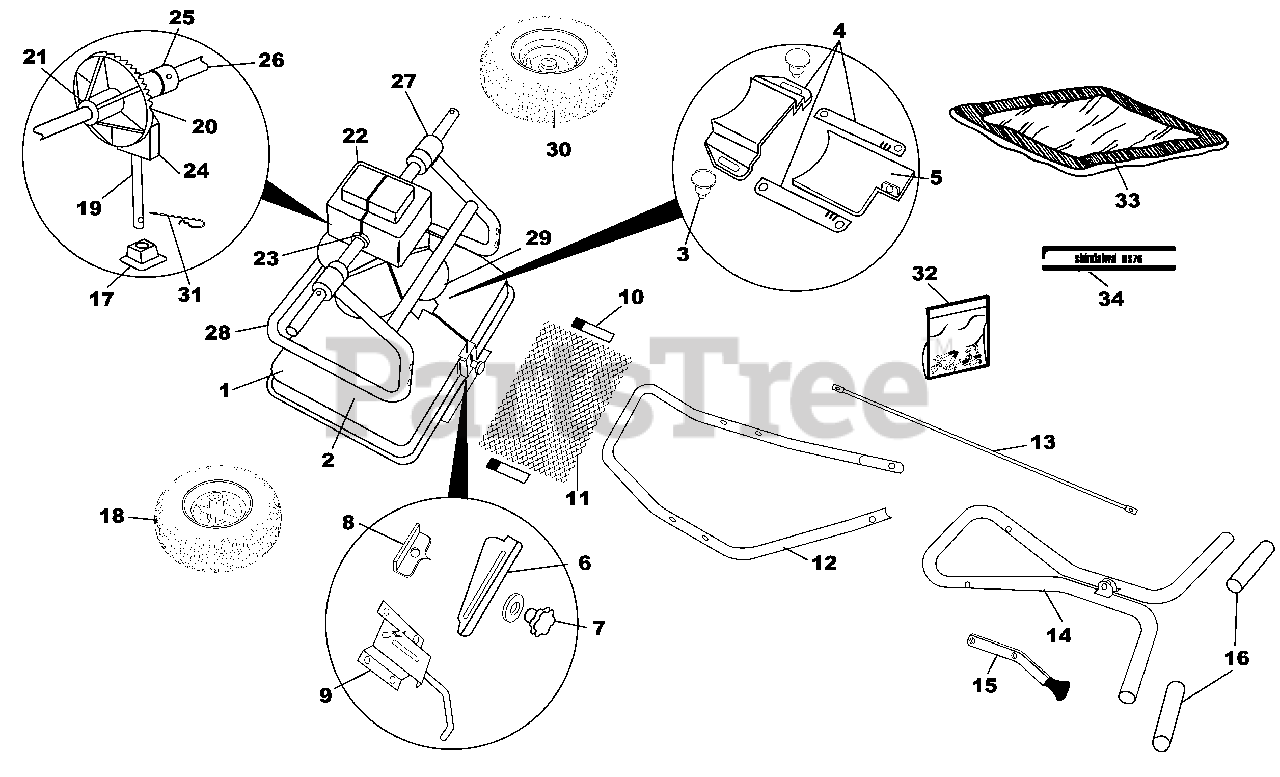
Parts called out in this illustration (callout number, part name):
1	Hopper Assembly
2	Hopper
3	Discharge Chute Knob
4	Discharge Chute & Shut-Off Plate Guides
5	Shut-Off Plate
6	Rate Plate
7	Rate Control Knob
8	Pointer
9	Spring Housing Assembly
10	Screen Clips
11	Hopper Screen
12	Handle Brace/Leg
13	Control Tube
14	Upper Handle
15	Handle Lever Assembly
16	Handle Grip
17	Impeller Shaft Bearing
18	Drive Wheel
19	Impeller Shaft
20	Pinion Gear
21	Axle Gear
22	Gear Cover
23	Gear Cover Clamps
24	Gear Support
25	Axle Collar w/Set Screw
27	Axle Bearing
28	Frame Assembly
29	Impeller
30	Free Wheel
31	Agitator
32	Fastener Package
33	Hopper Cover
34	Hopper Label
